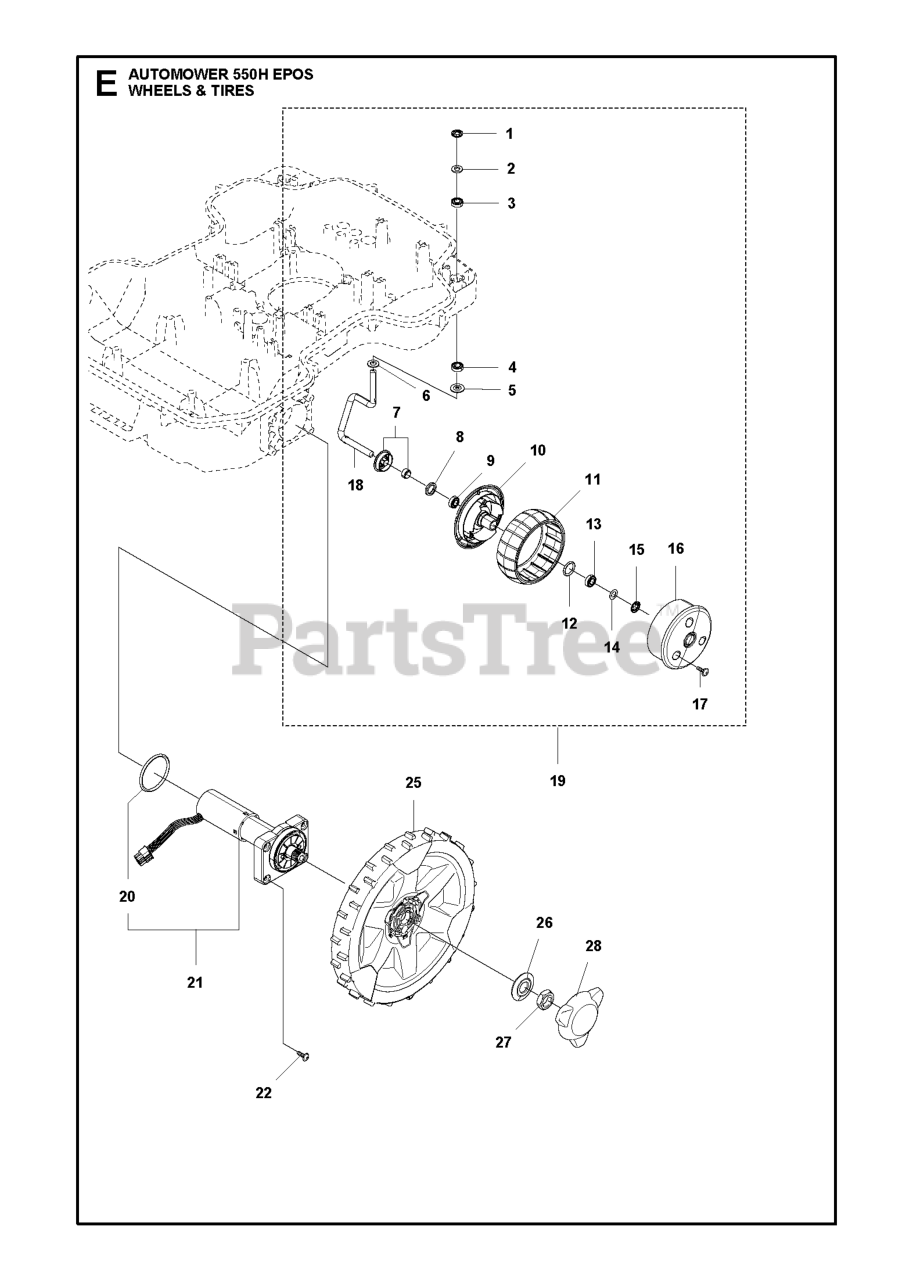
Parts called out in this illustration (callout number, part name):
1	LOCKWASHER PUSH-ON TYPE P 8 BV
2	WASHER DIN 988 13X8X0.5
3	BALL BEARING SINGLE ROW S688
4	BALL BEARING SINGLE ROW S688
5	WASHER FRONT WHEEL CENTER HOLE
6	WASHER DIN 988 13X8X0.5
7	SHIELD KIT
8	SEALING 12X18X3
9	BALL BEARING SINGLE ROW S688
10	WHEEL FRONT WHEEL INSIDE
11	WHEEL RUBBER TYRE
12	O-RING 2,62X15,54
13	BALL BEARING SINGLE ROW S688
14	WASHER DIN 988 13X8X0.5
15	LOCKWASHER PUSH-ON TYPE P 8 BV
16	WHEEL FRONT WHEEL OUTSIDE
17	SCREW 14MM
18	SPINDLE SPINDLE FRONT WHEEL RI
19	Wheels
20	O-RING LIGHT GREY
21	Motor
22	SCREW ITXPANT
25	WHEEL ASSY D249 HVA LIGHT GREY
26	WASHER WASHER REAR WHEEL 16X40
27	HEXAGON THIN NUT
28	HUB CAP REAR WHEEL NO CENTER P
